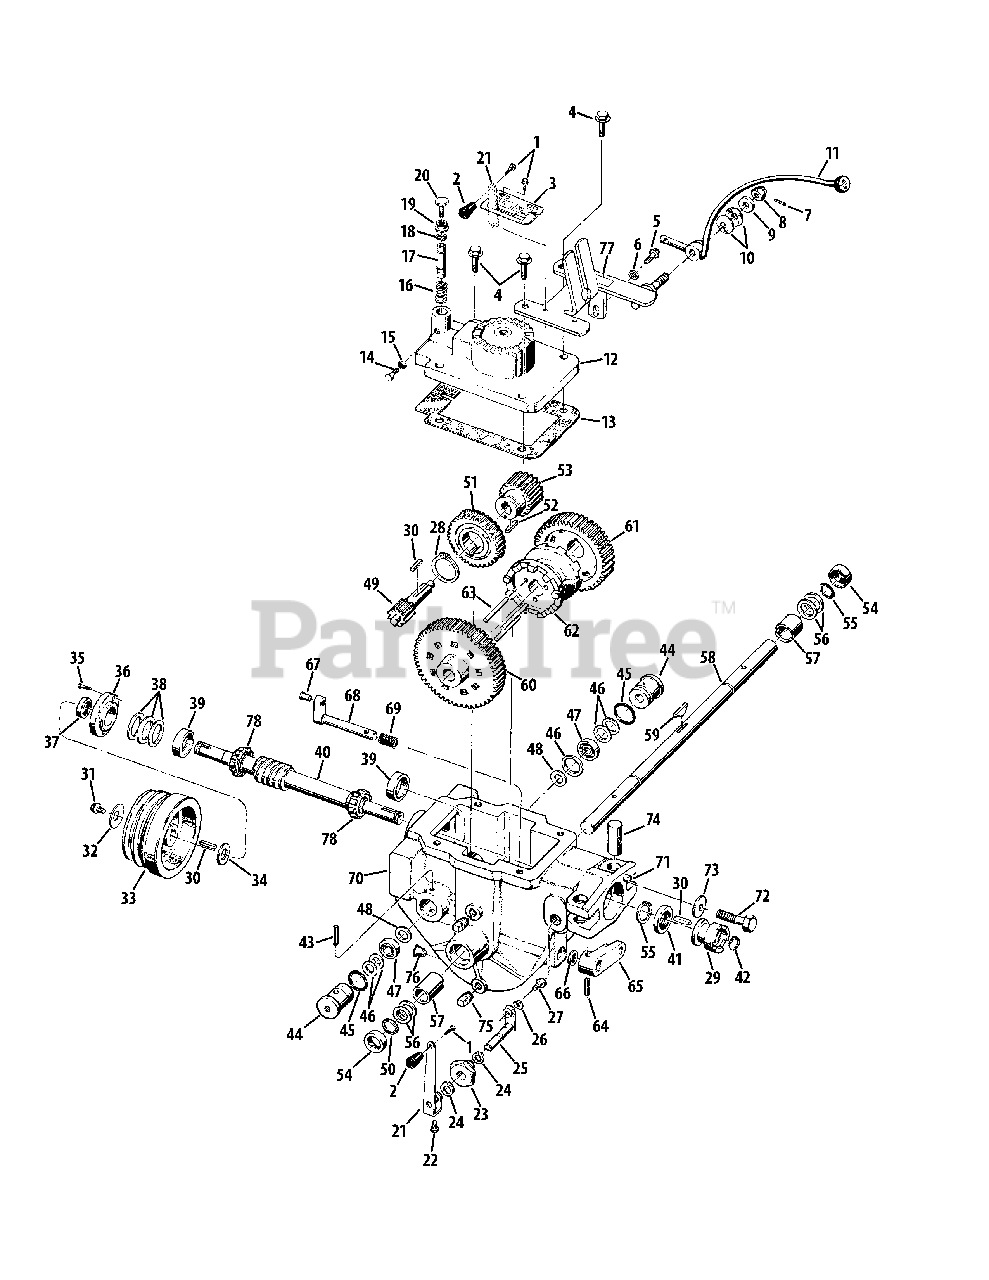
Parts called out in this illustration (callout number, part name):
1	Hex Head Screw, #10-32 x 3/8"
4	Hex Flange Bolt, 3/8-16 x 1-1/2"
5	Hex Flange Bolt, 5/16-18 x 3/4"
6	Flat Washer, 5/16"
7	Spring Pin, 1/8"
8	Hex Nut, 1/2-20
8	Flat Washer, .510 x 1.0 x .125
9	Shoulder Washer, 1.25 x .50 x .25
10	Disc Spring Washer, 1.97 x 1.0 x .118
11	Wheel Speed Shift Lever
12	Power Unit Transmission Cover
13	Transmission Cover Gasket
14	Hex Head Screw, 5/16-18 x 1"
15	Hex Nut, 5/16-18
16	Plunger Spring
18	Clip Ring
19	Flange Lock Nut, 3/8-16
20	Screw, 3/8-16 x 1-1/2"
21	Tines/PTO Clutch Lever
22	Hex Head Screw, 1/4-20 x 1/2"
23	Tines/PTO Clutch Bushing
24	External Retaining Ring
25	Tines/PTO Clutch Shaft
26	Hi-Collar Lockwasher, 1/4"
27	Socket Head Screw, 1/4-20 x 3/8"
28	External Retaining Ring
29	Dog Clutch
30	Key, 3/16" x 1"
31	Hex Head Screw, 5/16-24 x 3/4"
32	Spring Washer, .827 x .331 x .098
33	Transmission Drive Pulley
34	Flat Washer, 1.25 x .687 x .075
35	Flange Nut, 1/4-20 x .75
36	Front Bearing Cap
38	Flat Washer, 1.175 x 1.5 x .062
38	Flat Washer, 1.175 x 1.5 x .005
38	Flat Washer, 1.175 x 1.5 x .03
38	Flat Washer, 1.175 x 1.5 x .01
39	Cup Bearing
40	Main Drive Shaft
42	Retaining Ring
43	Roll Pin (Spirol), 1/4" x 2
44	Pinion Bearing
46	Flat Washer, 1.234 x 1.015 x .062
46	Flat Washer, 1.234 x 1.015 x .033
46	Flat Washer, 1.234 x 1.015 x .01
47	Ball Bearing
48	Washer
49	Pinion Stem
50	External Retaining Ring, 1.387 ID
51	Worm Gear
52	Key, 3/16" x 5/8"
53	Fast Speed Pinion Gear
55	External Retaining Ring
56	Flat Washer, 1.375 x 1.015 x .005
56	Flat Washer, 1.375 x 1.015 x .01
56	Flat Washer, 1.375 x 1.015 x .015
56	Flat Washer, 1.375 x 1.015 x .03
56	Flat Washer, 1.375 x 1.015 x .062
57	Bushing, 1.25 x 1.005 x 1.5
58	Wheel Shaft
59	Hi-Pro Key, .250 x 1.8125
60	Slow Speed Gear
61	Faste Gear Speed
62	Dog Clutch
63	Clutch Guide Pin, 1/4"
64	Spring Pin, 3/16" x 1-1/4"
65	Wheel Speed Shifting Lever
67	Wheel Speed Shifting Pin
68	Wheel Speed Shifting Shaft
70	Transmission Housing
71	Alignment Pin
72	Hex Screw, 1/2-13 x 2"
73	Disc Spring Washer
75	Pipe Plug, 1/4"
76	Plug-Red Plastic
77	Clutch Bracket
78	Cone Bearing
